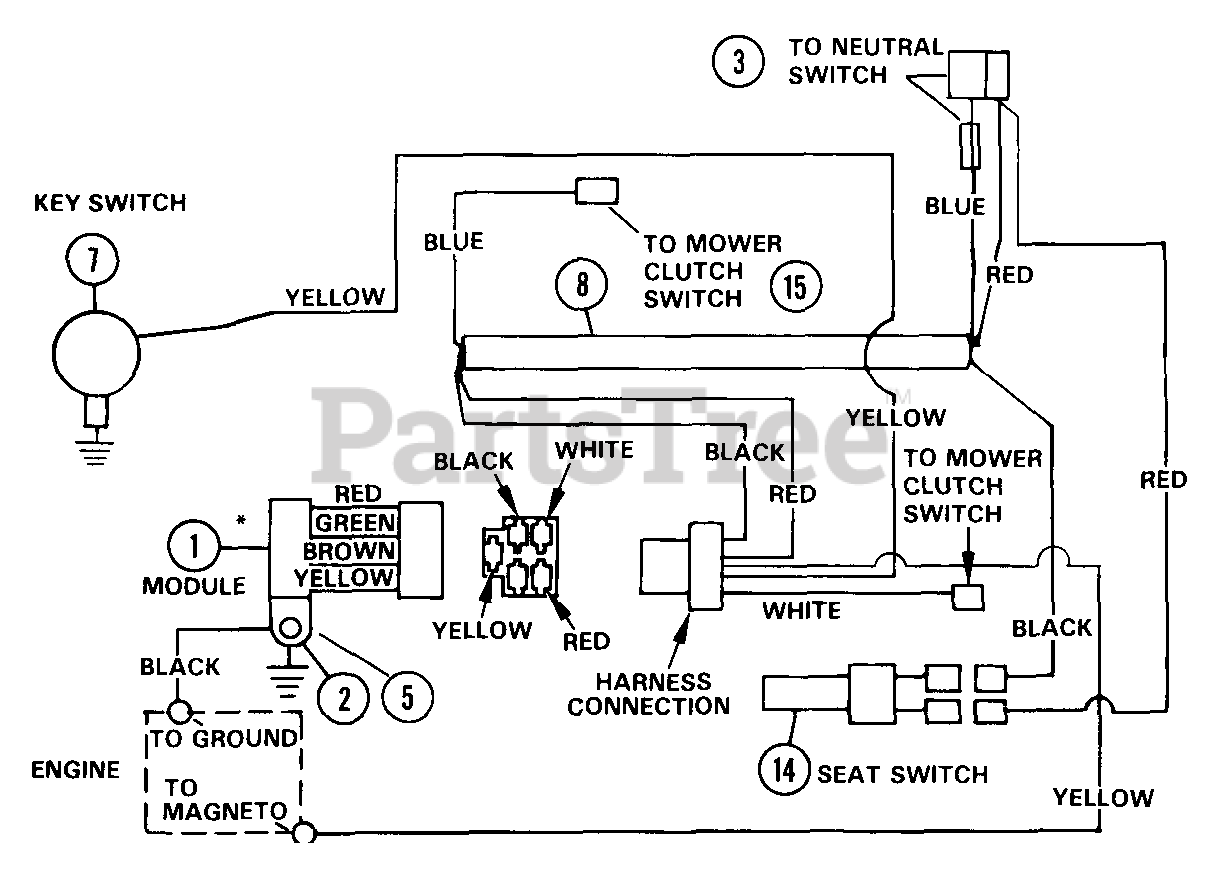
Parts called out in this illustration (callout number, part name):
1	MODULE
2	SCR-MCH 10-24X.62 SLRH PL
3	SWITCH-NEUTRAL START N.O.
5	NUT-KEPS 10-24 PL
7	IGNITION SWITCH AND KEY ASSEMB
8	WIRE HARNESS
11	KEYS
14	SWITCH SEAT
15	SWITCH INTERLOCK
